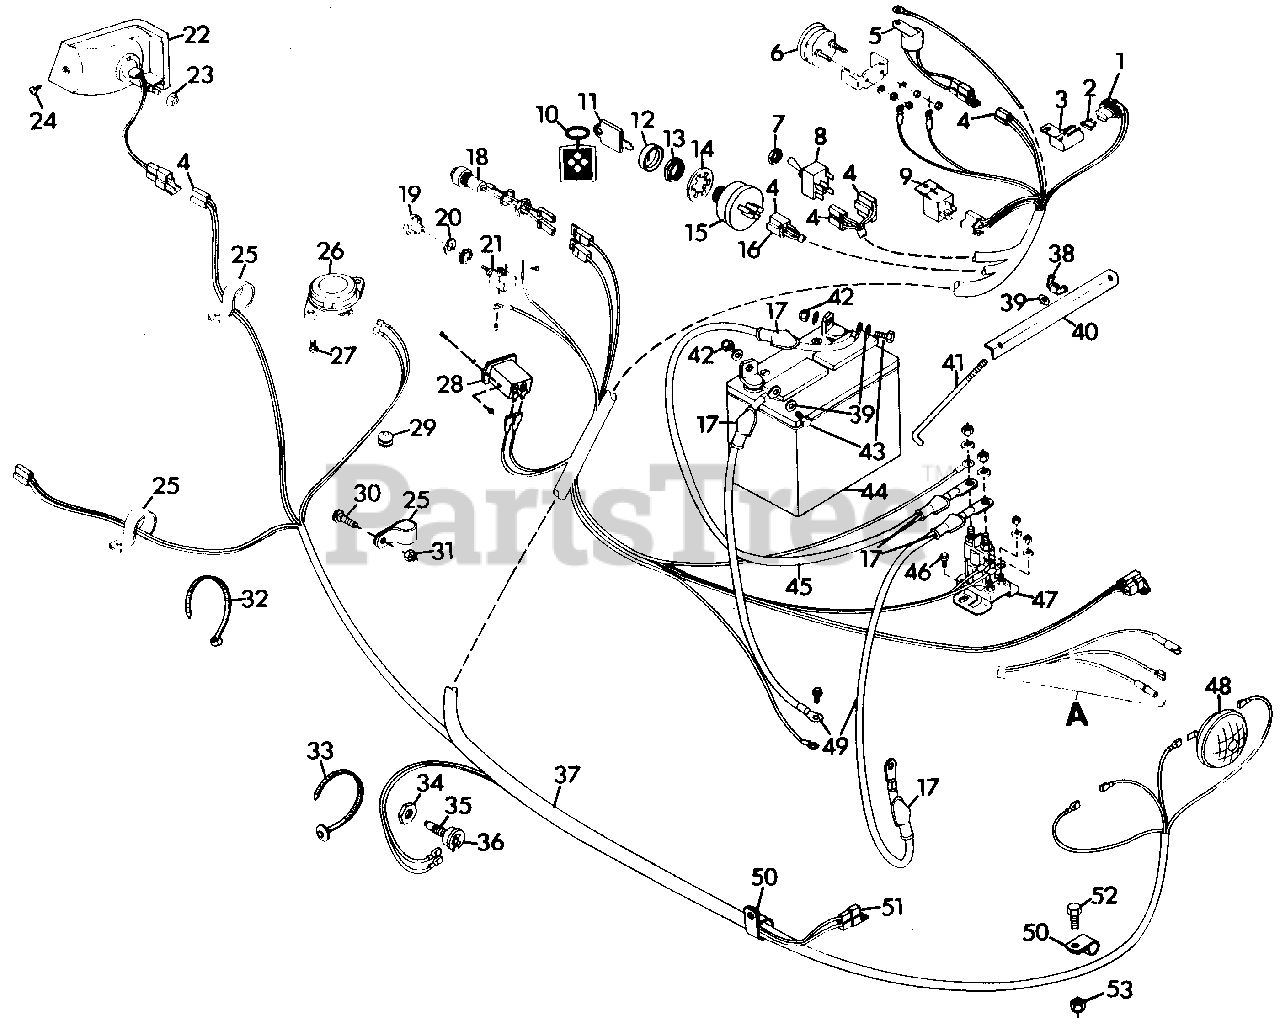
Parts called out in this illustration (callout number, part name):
1	Terminal, for 10-12 Ga. Wire
2	Fuse, 25 Amp
3	Cover
4	Terminal
6	Gauge, Ammeter
7	Nut, 1/2-27
8	Switch, PTO
9	Relay
10	Chain, Key
11	Key, Ignition Switch
12	Boot, For 9/16 Switch Nut
13	Nut, 9/16-24 For Switch
14	Washer, Lock
15	Switch, Ignition
16	Connector
17	Boot, Battery Cable
18	Light, Indicator
19	Knob, Light Switch
20	Nut, Special Light Switch
21	Switch, Light
22	Tail Light, R.H.
22	Tail Light, L.H.
23	Palnut, 1/4
24	Screw, Tap 10-12 x .50 PHDCR
25	Clamp, Cushioned Steel
26	Switch, Seat
27	Screw, Mach. 1/4-20 x .50
28	Hourmeter
29	Grommet
30	Bolt, Carriage 5/16-18 x 1.00
31	Nut, Lock 5/16-18
32	Tie Wrap, Black
33	Clamp, Universal
34	Nut, Hex 5/8-32
35	Boot
36	Switch
37	Harness, Wiring
38	Nut, Wing 1/4-20
39	Washer, Flat .281 x .625 x .065
40	Hold Down, Battery
41	Hook, Battery Hold Down
42	Nut, Lock 1/4-20
43	Bolt, Hex 1/4-20 x .750
44	Battery, 12 Volt Small
45	Cable, Battery To Solenoid
46	Screw, 1/4-20 x .50 Self Tapping
47	Switch, Magnetic
48	Headlight
49	Cable, Negative Battery 8HP
50	Clamp, Steel .625
51	Connector
52	Bolt, Hex 3/8-16 x .875
53	Nut, Lock 3/8-16
